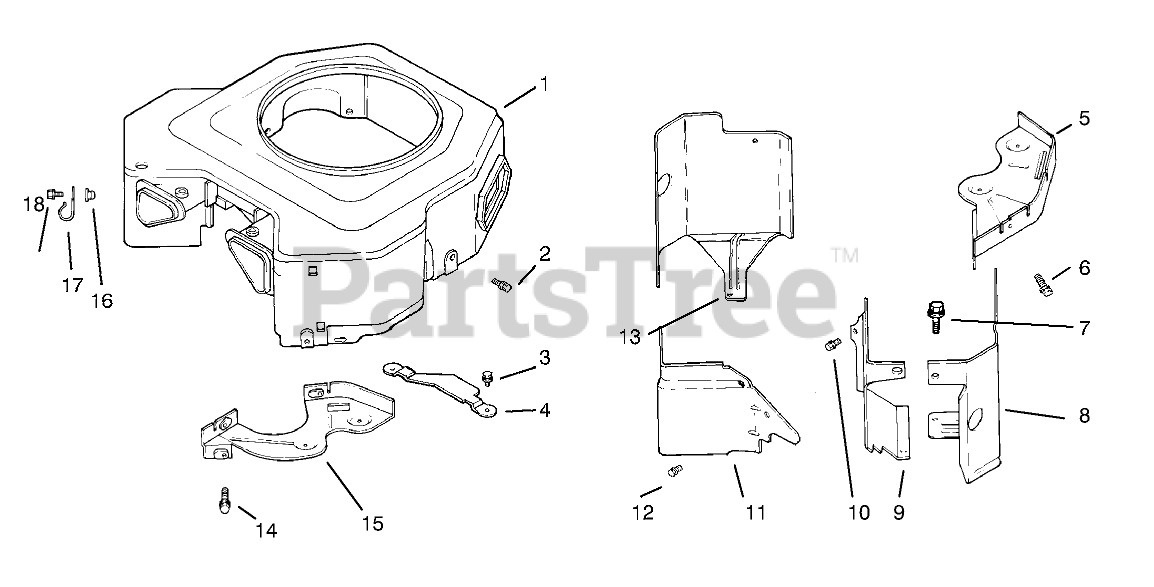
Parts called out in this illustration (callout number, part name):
1	Blower Housing ASM
3	Screw
4	Guard-Flywheel
5	Plate-Backing #2 Side
7	Screw
8	Baffle-Cylinder, #2
9	Baffle-Valley #1 Side
10	Screw
11	Baffle-Valley #2 Side
13	Baffle-Cyl. #1 Side
14	Screw
15	Plate-Backing #1
16	Nut
17	Clamp
18	Screw
